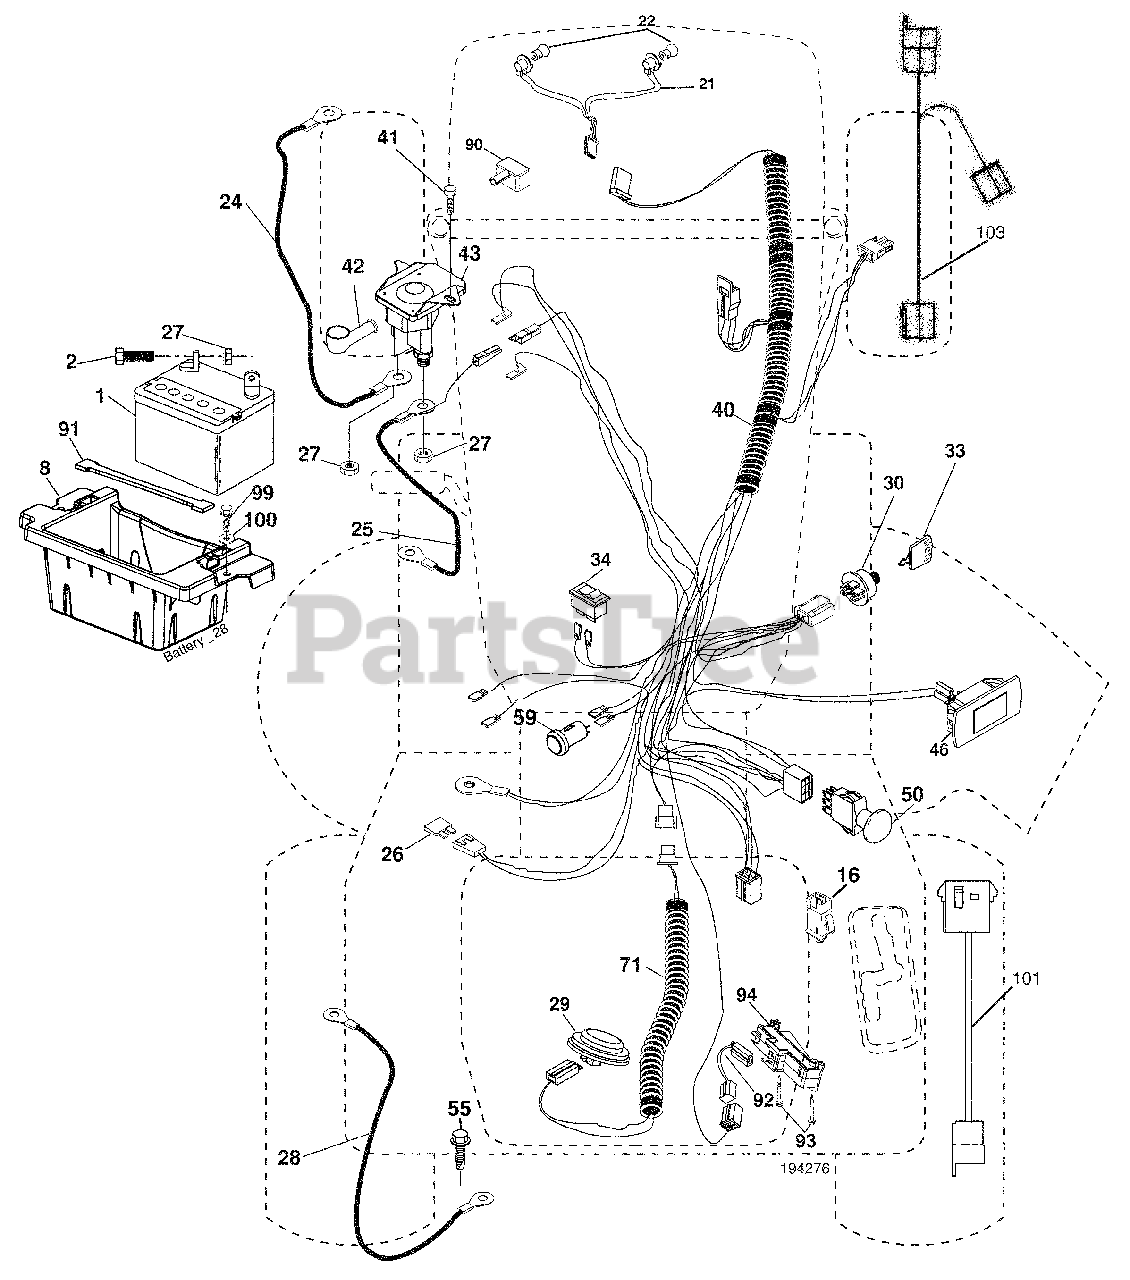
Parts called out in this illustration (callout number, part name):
1	Battery
2	Bolt Hex Hd 1/4-20 unc x 3/4
8	Battery Box
16	Switch Interlock
21	Harness Socket Light
22	Bulb, Light # 1156
24	Cable Battery
25	Cable Starter
27	Nut Keps Hex 1/4-20 unc
28	Cable Ground 21" Blk 6 Ga.
29	Switch Seat
30	Switch Ign
33	Key Ign Molded Generic
34	Switch Light/Reset
40	Harness Ign
41	Screw Thd Cut 1/4-20 x 1/2
42	Cover Terminal Red
43	Solenoid
46	Gauge Hourmeter
50	Switch PTO
55	Screw Thdrol 5/16-18 x 3/4
59	Outlet 12-Volt
71	Harness Ign. Dash
90	Cover Terminal Battery
91	Strap Battery
92	Harness Pigtail
93	Screw Plastite 10-14 x 2.0
94	Module Reverse ROS
99	Screw Hexwsh Thdrol 1/4-20 x 3/4
100	Washer 9/32 x 7/8 x 16 Ga.
101	Pigtail MATNLK Harness
103	Harness Pigtail 12V outlet
